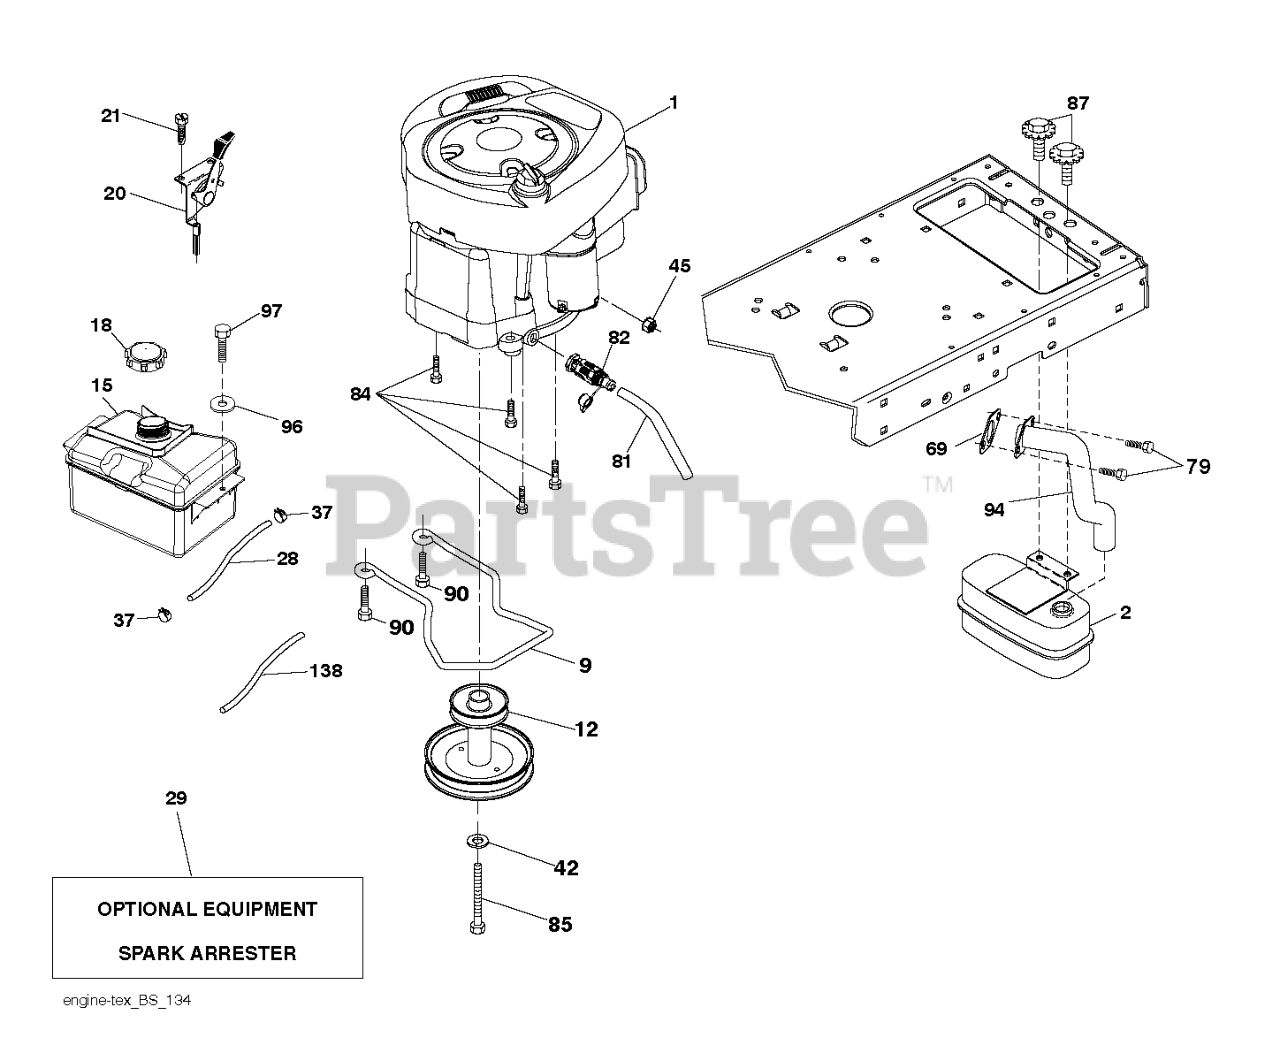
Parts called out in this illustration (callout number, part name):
2	MUFFLER.ASM.SINGLE
9	KEEPER.BELT.ENG.4.25"2.BLT.431
12	ENGINE.PULLEY
15	TANK.ASM.FT.2.5GAL.W/CAP.EPA17
18	FUEL.CAP.ASM.2.25TETHRED.RATCH
20	CONTROL.TH/CK.C.
21	SCREW.#10 X 0.750.BOS (2 2)
28	LINE.FUEL.20"FRONT.EMI
29	Arrester, Spark (Optional equipment) (AYP part number)
37	Clamp Hose Black (AYP part number)
42	WASHER 7/16 LOCK
45	Nut Keps Hex 1/4 - 20 UNC (AYP part number)
69	REPL BY 532 27 22-93
79	SCREW.SOCKET HD.5/16-1
81	TUBE, DRAIN OIL ASM.
82	VALUE.OIL.DRAIN
84	SCREW.3/8-16
85	Speed Clip
87	BOLT, 5/16-18 X 1 3/4
90	SCREW 3/8-16X1
94	EXHAUST.TUBE.B&S.28/31
96	Washer 9/32 x 7/8 x 16 Gauge (AYP part number)
97	SCREW HEXWSHR 1/4-20X3/4
138	RP PURGE LINE
